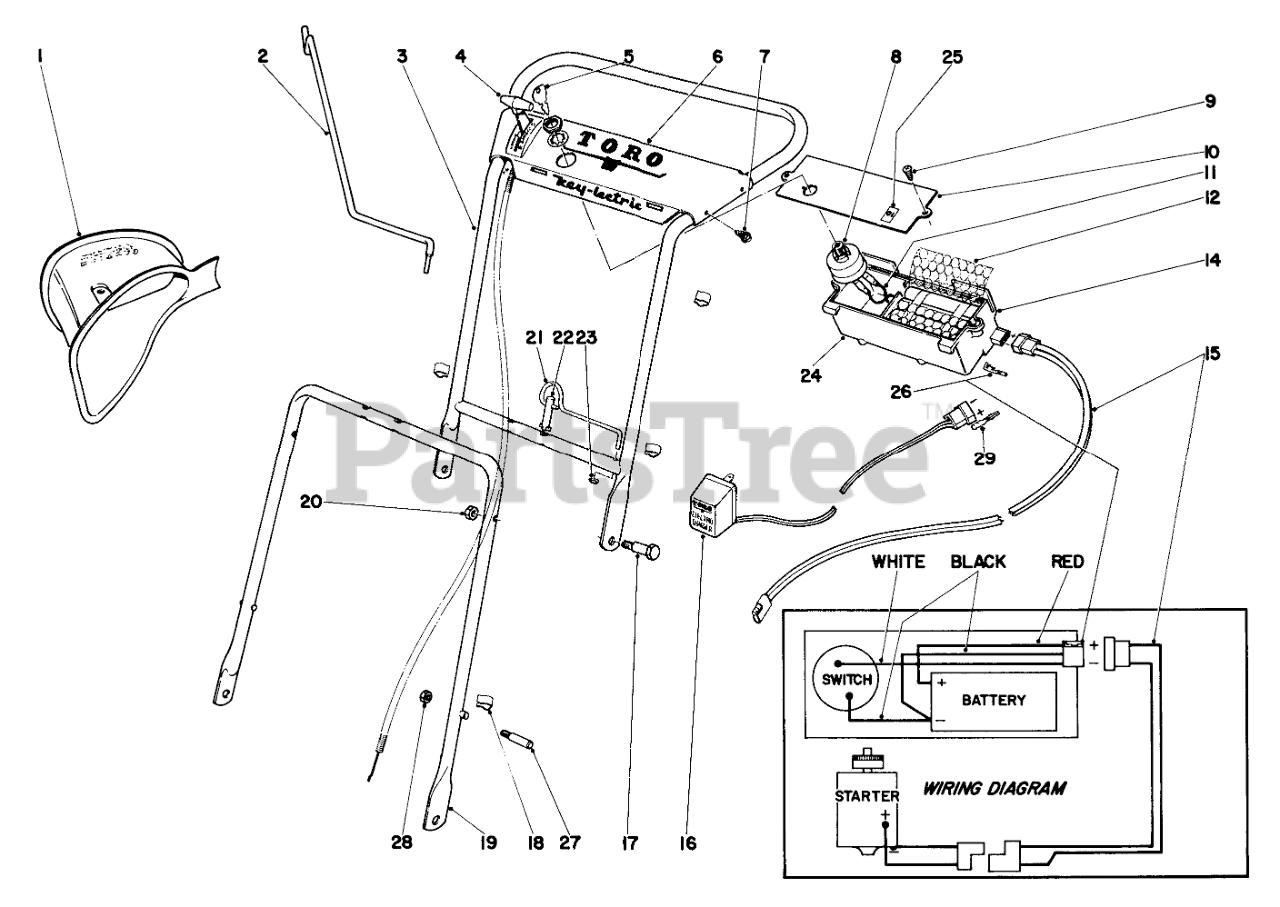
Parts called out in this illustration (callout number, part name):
1	Attachment Bag
2	GRASS BAG HANGER
3	Handle-Upper
4	Throttle Control
5	Key
6	Plate, Escutcheon
7	SCREW-HWHTF
8	Switch, Starter
9	Self Tapping Screw
10	Cover, Battery Pack
11	Lead Wire
12	Spacer-Battery
14	Container Battery Pack
15	Harness
16	Charger, Battery
17	Screw
18	CONTROL WIRE CLIP
19	Handle-Lower
20	Nut
21	Pin, Latch
22	Pin, Latch
24	Battery Pack Assy. (Incl. Ref. 11, 12 & 14)
25	Decal
26	Terminal
27	Handle Pin
28	Nut
29	Terminal Pin
